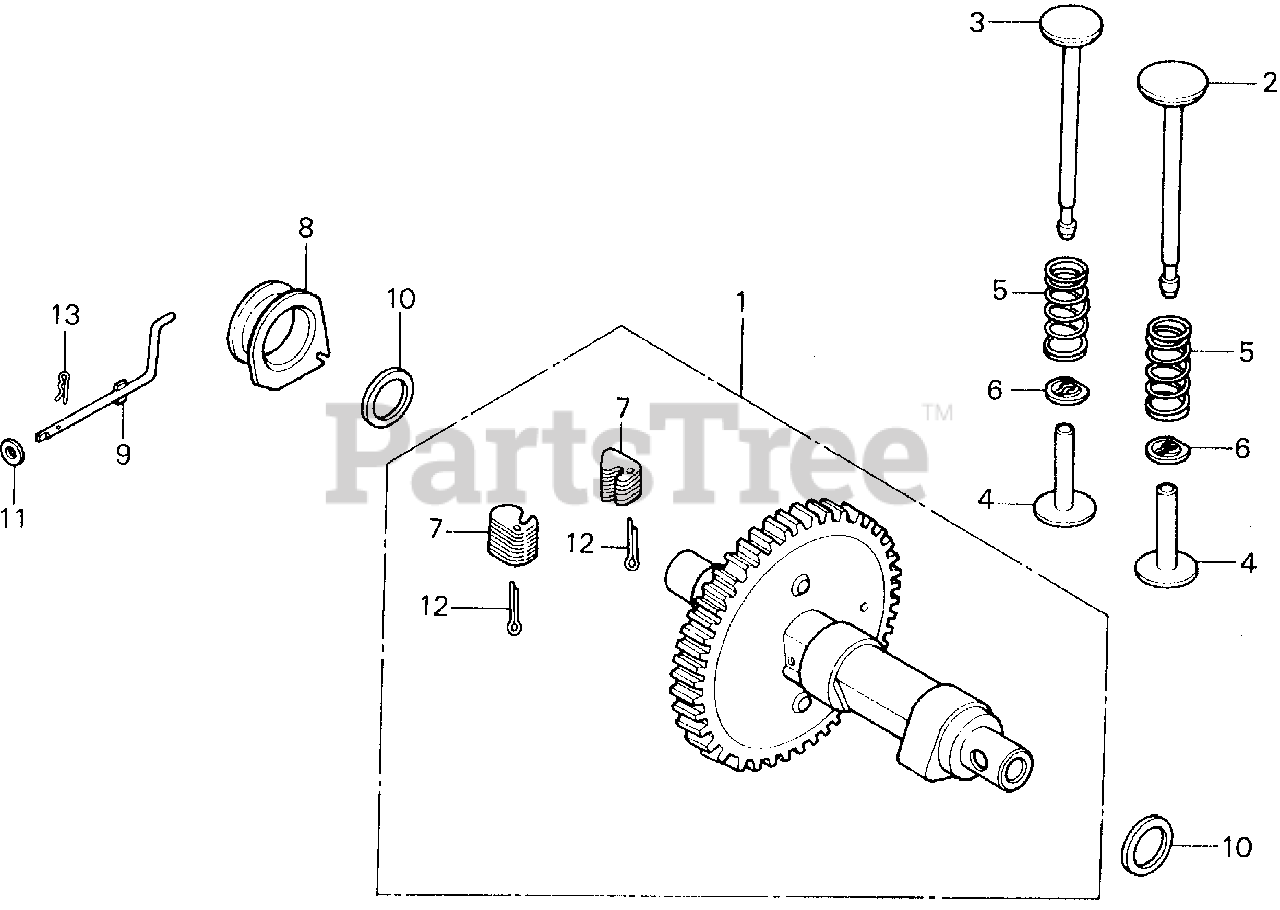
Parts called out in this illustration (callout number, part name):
1	CAMSHAFT ASSY.
2	VALVE, IN.
3	VALVE, EX.
4	LIFTER, VALVE (39.6MM)
4	LIFTER, VALVE (39.9MM)
5	SPRING, VALVE
6	RETAINER, VALVE SPRING
7	WEIGHT, GOVERNOR
8	SLIDER, GOVERNOR
9	SHAFT, GOVERNOR ARM
10	WASHER, THRUST (18MM)
11	WASHER, PLAIN (5MM)
12	PIN, SPLIT (3.0X25)
12	PIN, SPLIT (3.0X45)
13	PIN, LOCK (8MM)
